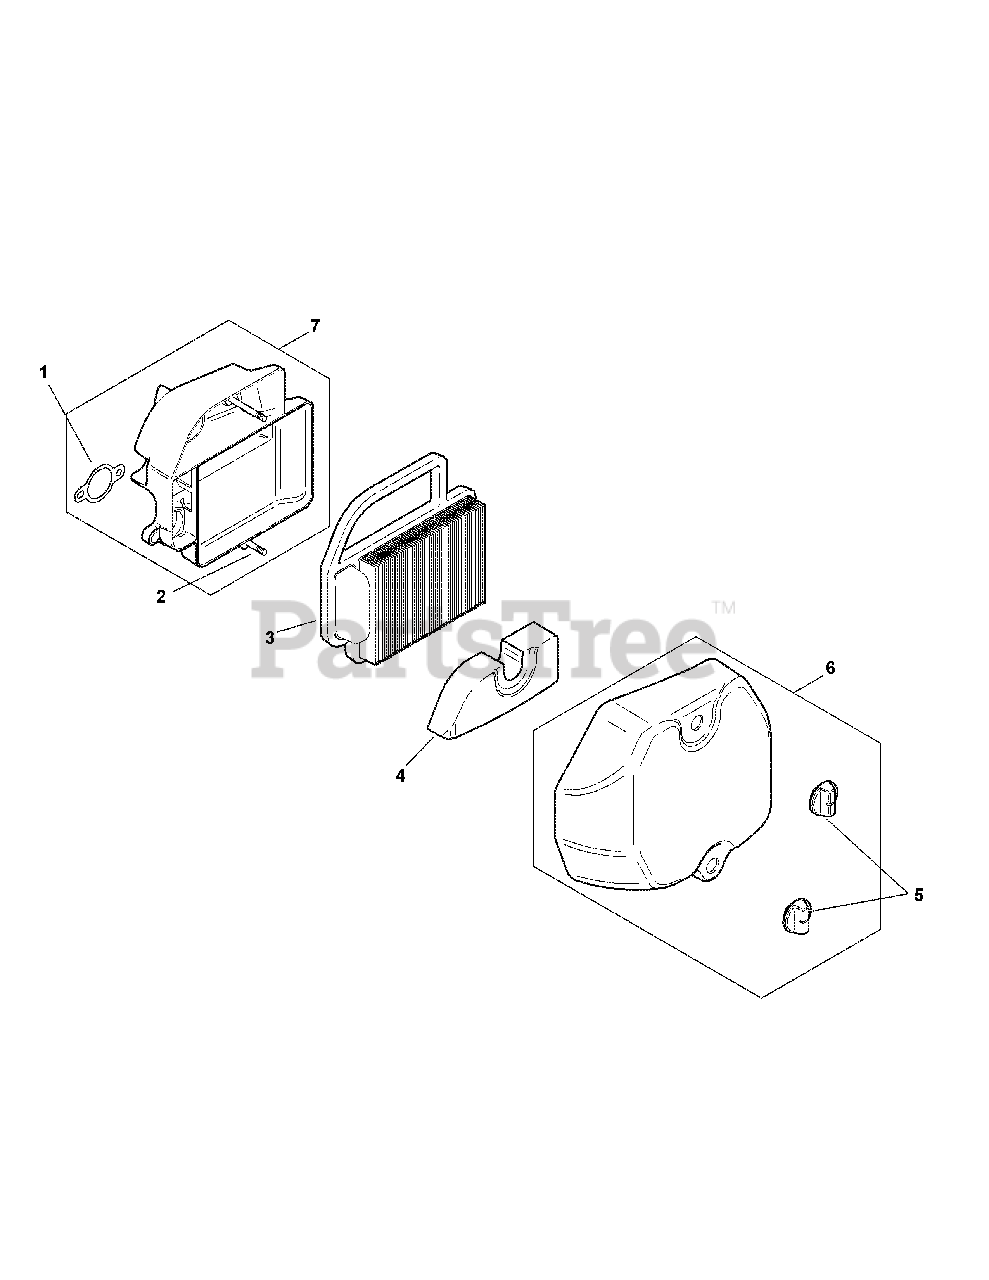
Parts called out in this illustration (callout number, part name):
1	Gasket, Air Cleaner Base
2	Stud, Air Cleaner Base
3	Element, Air Cleaner
4	Pre-Cleaner Element (Dry)
6	Air Clnr Base
7	Kit, Air Cleaner Cover
